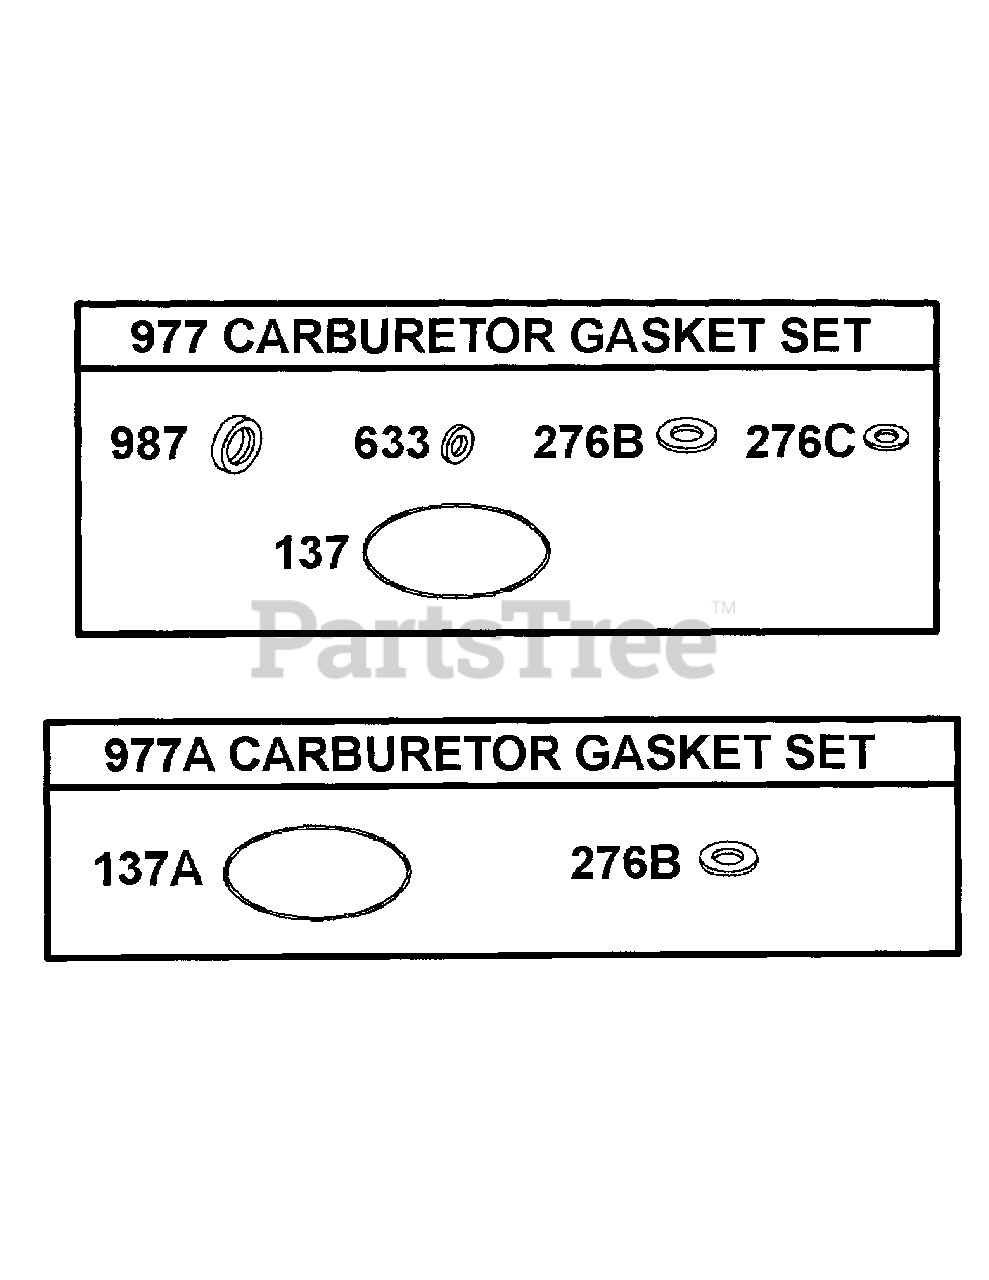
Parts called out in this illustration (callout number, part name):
137	Gasket-Float Bowl
276B	Washer-Sealing (Float Bowl)
276C	Washer-Sealing (Carburetor Plug)
633	Seal-Choke/throttle Shaft
977	Gasket Set-Carburetor
977A	Gasket Set-Carburetor
987	Seal-Throttle Shaft
